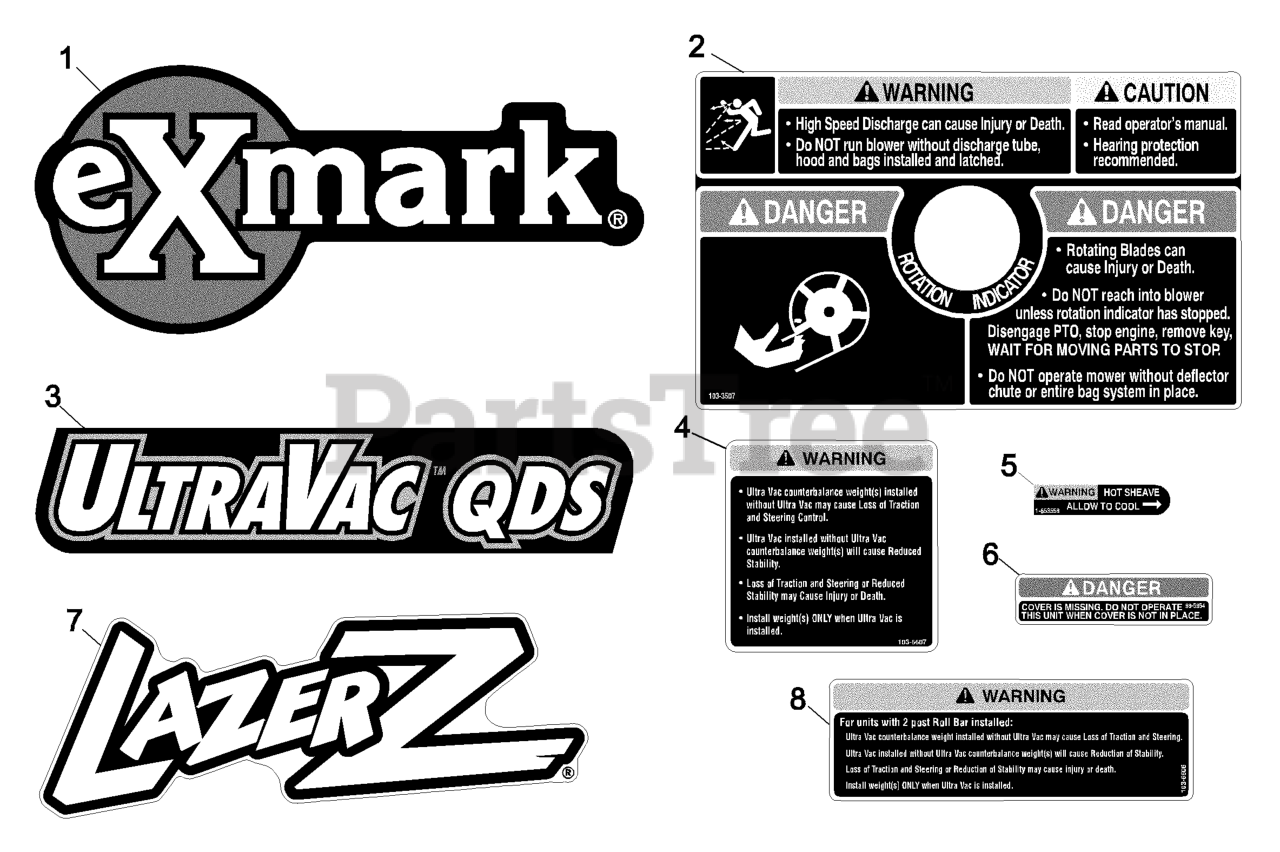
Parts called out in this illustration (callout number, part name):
1	DECAL, EXMARK
3	DECAL, ULTRAVAC QDS
4	DECAL,WEIGHT
5	DECAL-WARNING
6	DECAL-COVER, MISSING
7	DECAL,LAZER MODEL
8	DECAL,WEIGHT
